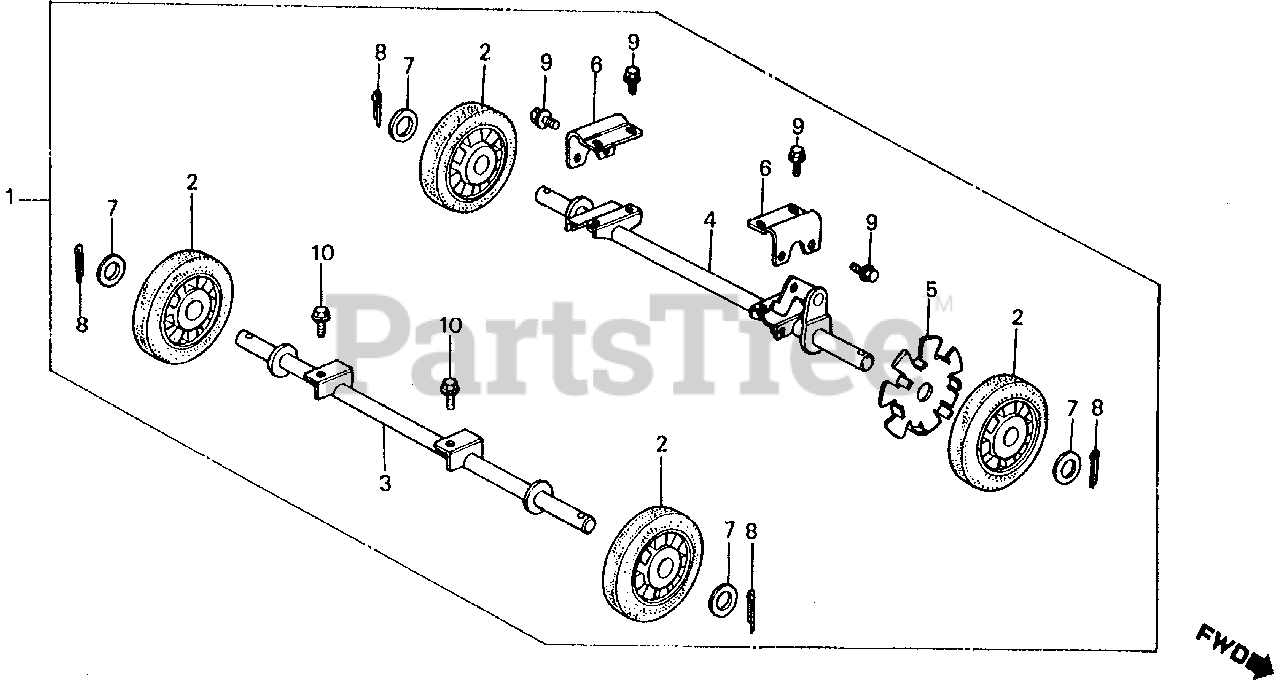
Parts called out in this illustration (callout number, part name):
2	WHEEL
3	SHAFT, R. WHEEL
4	SHAFT, L. WHEEL
5	PLATE, LOCK
6	PLATE, PIPE SETTING
7	WASHER, FLAT (20MM)
8	PIN, COTTER (4.0X30)
9	BOLT, FLANGE (6X14)
10	BOLT, FLANGE (8X16)
